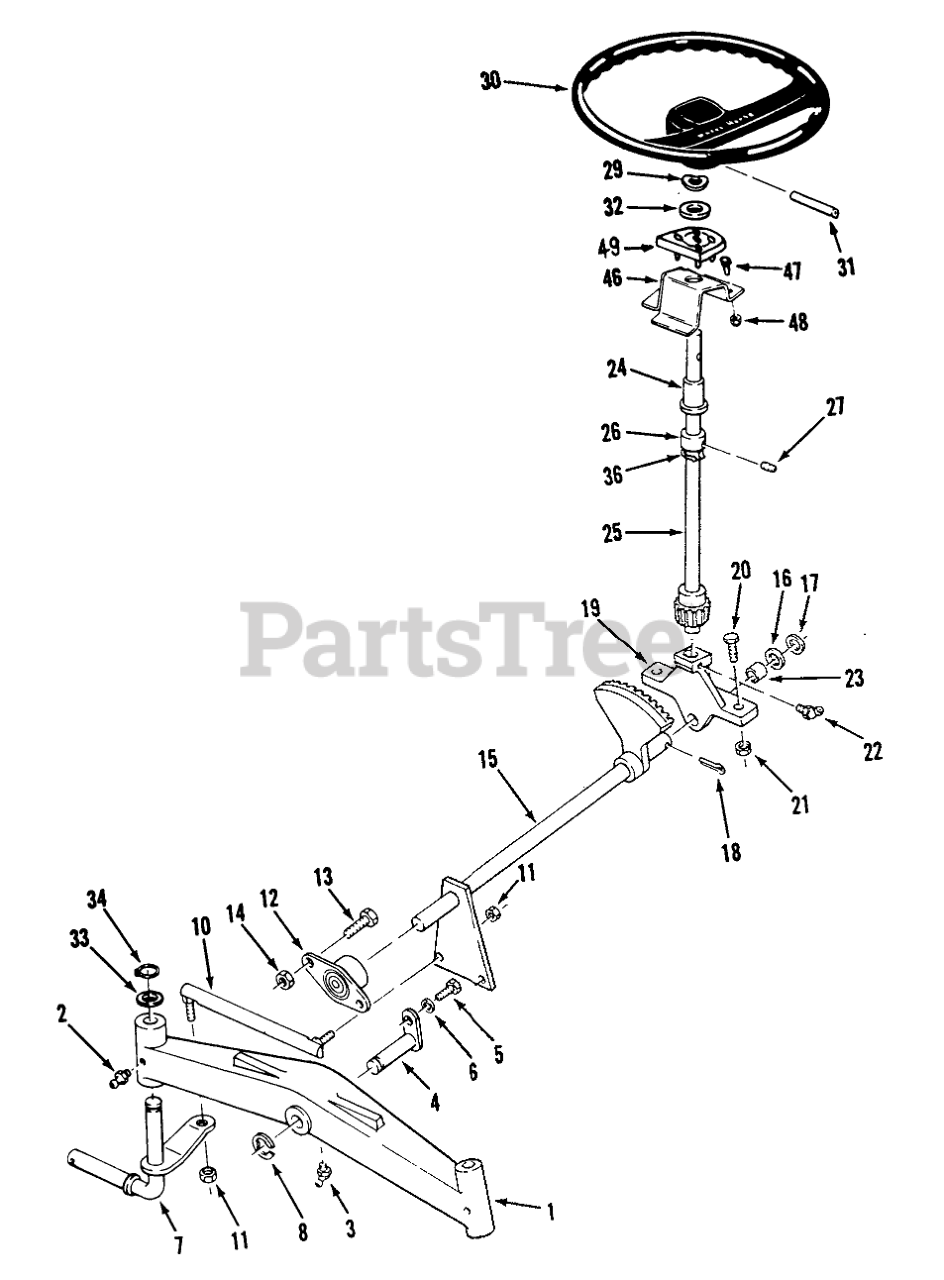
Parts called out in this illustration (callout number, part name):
1	AXLE-FRONT
2	Zerk
3	FITTING-GREASE
4	PIN AND PLATE ASM
5	H H C S
6	Lockwasher
7	RH SPINDLE WA
8	E-RING
10	Tie Rod RH
11	Nut
12	BEARING-FLANGED
13	Bolt
14	NUT
15	ASS'Y-STRG SHAFT R
16	WASHER-SHIM
17	WASHER
18	PIN-4
19	Support
20	Bolt
21	NUT
22	FITTING-GREASE
23	BEARING-BRONZE
24	BEARING-FLANGED
25	Shaft-Upper Steering
26	Collar
27	SCREW-SET
29	WASHER-BOWED
30	STEERING WHEEL-15"
31	Pin-Roll
32	WASHER-FLAT
33	WASHER
34	Snap Ring
36	RING-RETAINING
46	BRACKET-STEERING B
47	H H C S
48	Nut
49	COVER-STEERING SHAFT
